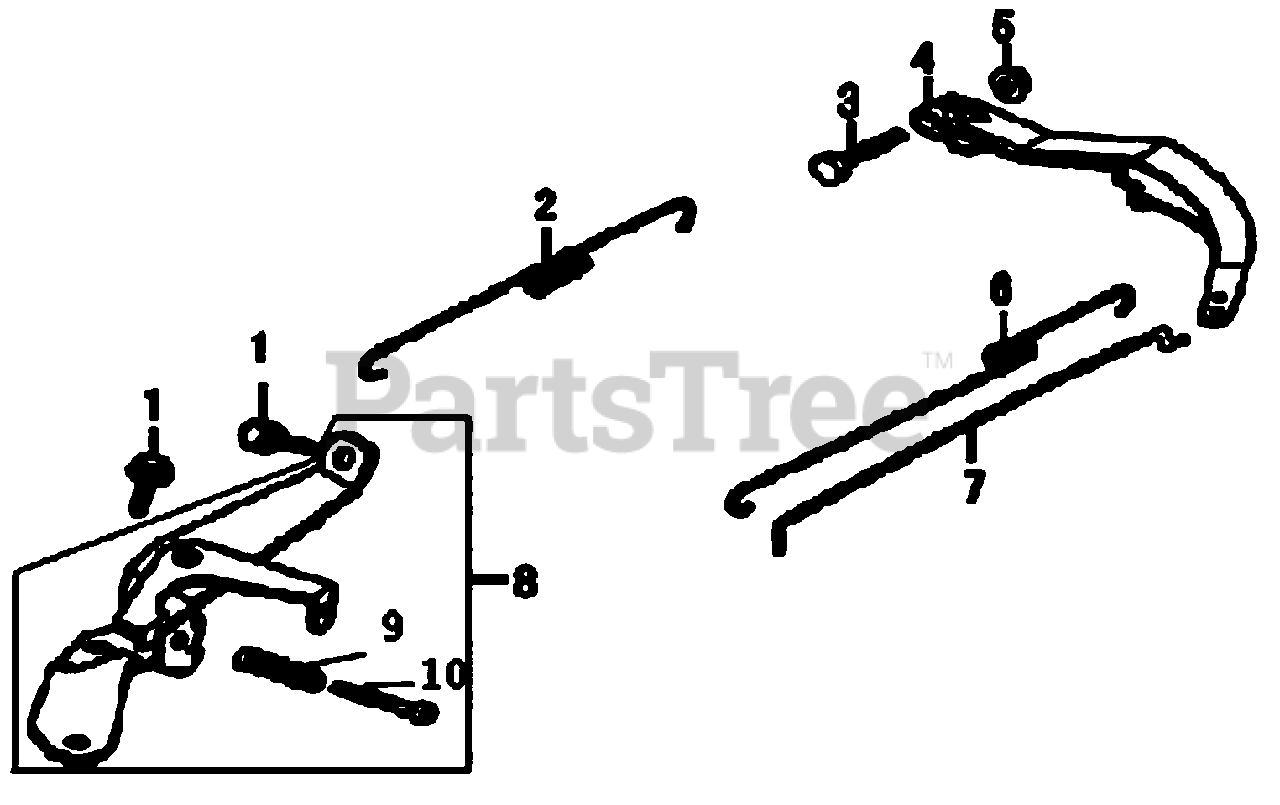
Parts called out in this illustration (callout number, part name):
1	BOLT, FLANGE
2	SPRING, GOVERNOR
3	BOLT, QUADRATE HEAD
4	ARM, GOVERNOR
5	NUT, FLANGE
6	SPRING, THROTTLE RETURN
7	ROD, GOVERNOR
8	CONTROL ASSY.
10	SCREW, 5x35
